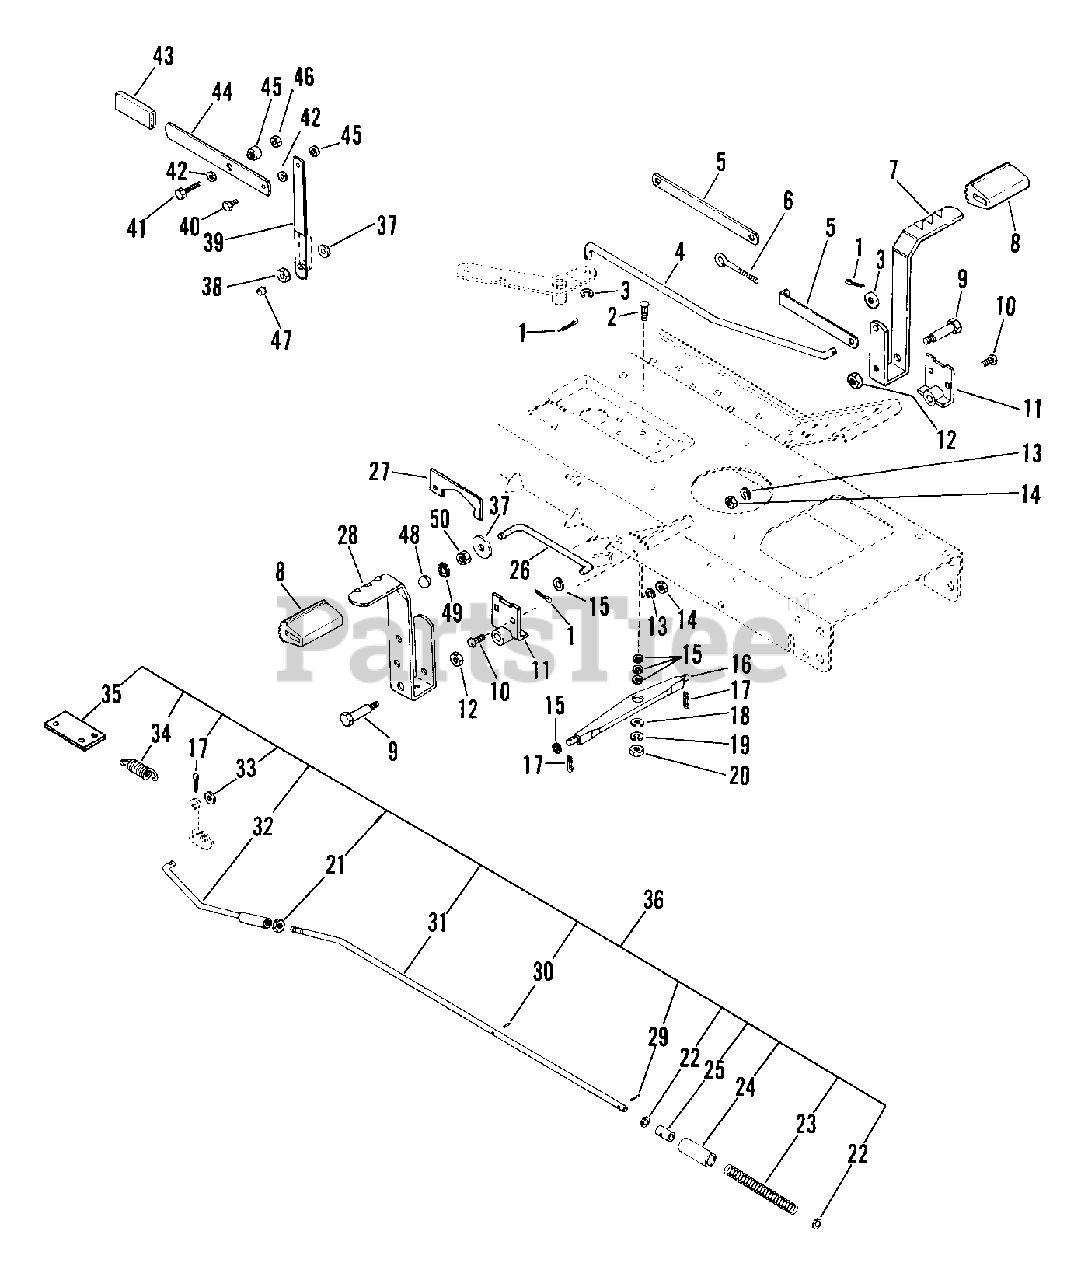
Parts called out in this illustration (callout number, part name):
1	PIN-COTR .12X.75 PL
2	BLT-RDHDSQNK .38-16X1.25 PL
3	WSHR-FL-STL .438X1.0X.083 PL
4	CLUTCH ROD
5	LINK
6	EYE-BOLT
7	CLUTCH PEDAL
8	PEDAL COVER
8	LINE,FUEL .5 OD X .25 ID
9	SHOULDER BOLT .50 X 1.75
10	BLT-RDHDSQNK .31-18X.75 GR5 PL
11	PEDAL PIVOT
12	NUT-LK-JAM-CTR .375-16 PL
13	WSHR-LK .312X.097 PL HVY
14	NUT-HEX .312-18
15	WSHR-FL-STL .380X.626X.033
16	PIVOT ARM
17	PIN-HAIR INT .08X.18X1.18
18	WSHR-FL-STL.406X.812X.065PL
19	WSHR-LK .375X.115 HVY PL
20	NUT-HEX .375-16
21	NUT .375-24 PL
22	WSHR-FL-STL .38X.875X.083 PL
23	SG-COMP .106X.63X 12.0 WLD 62
24	SLEEVE
25	SLEEVE
26	PARKING BRAKE ROD
28	BRAKE PEDAL
29	PIN-ROLL .125X.88
30	PIN-ROLL .125X.50
31	BRAKE ROD
32	BRAKE ROD
33	WSHR-FL-STL .323X.625X.062 PL
34	SG-TENS .072X.75X2.81 WLD ??
35	ANCHOR PLATE
36	BRAKE LINKAGE ASSEMBLY
37	WSHR-FL-STL .406X1.50X.049PL
38	NUT-LK-JAM-CTR .375-16 PL
39	LINK
40	BLT-HEX .25-20X.63 PL GR2
41	BLT-HEX .25-20X1.50 PL GR5
42	WSHR-FL-STL.281X.62X.065 PL
43	GRIP
44	ARM
45	SPACER-SHOULDER
46	NUT-LK-CTR .250-20 PL
47	GRIP
48	SHIFT BALL
49	WSHR-LK-EXT .375X.035 PL
50	NUT-JAM .375-16 PL
